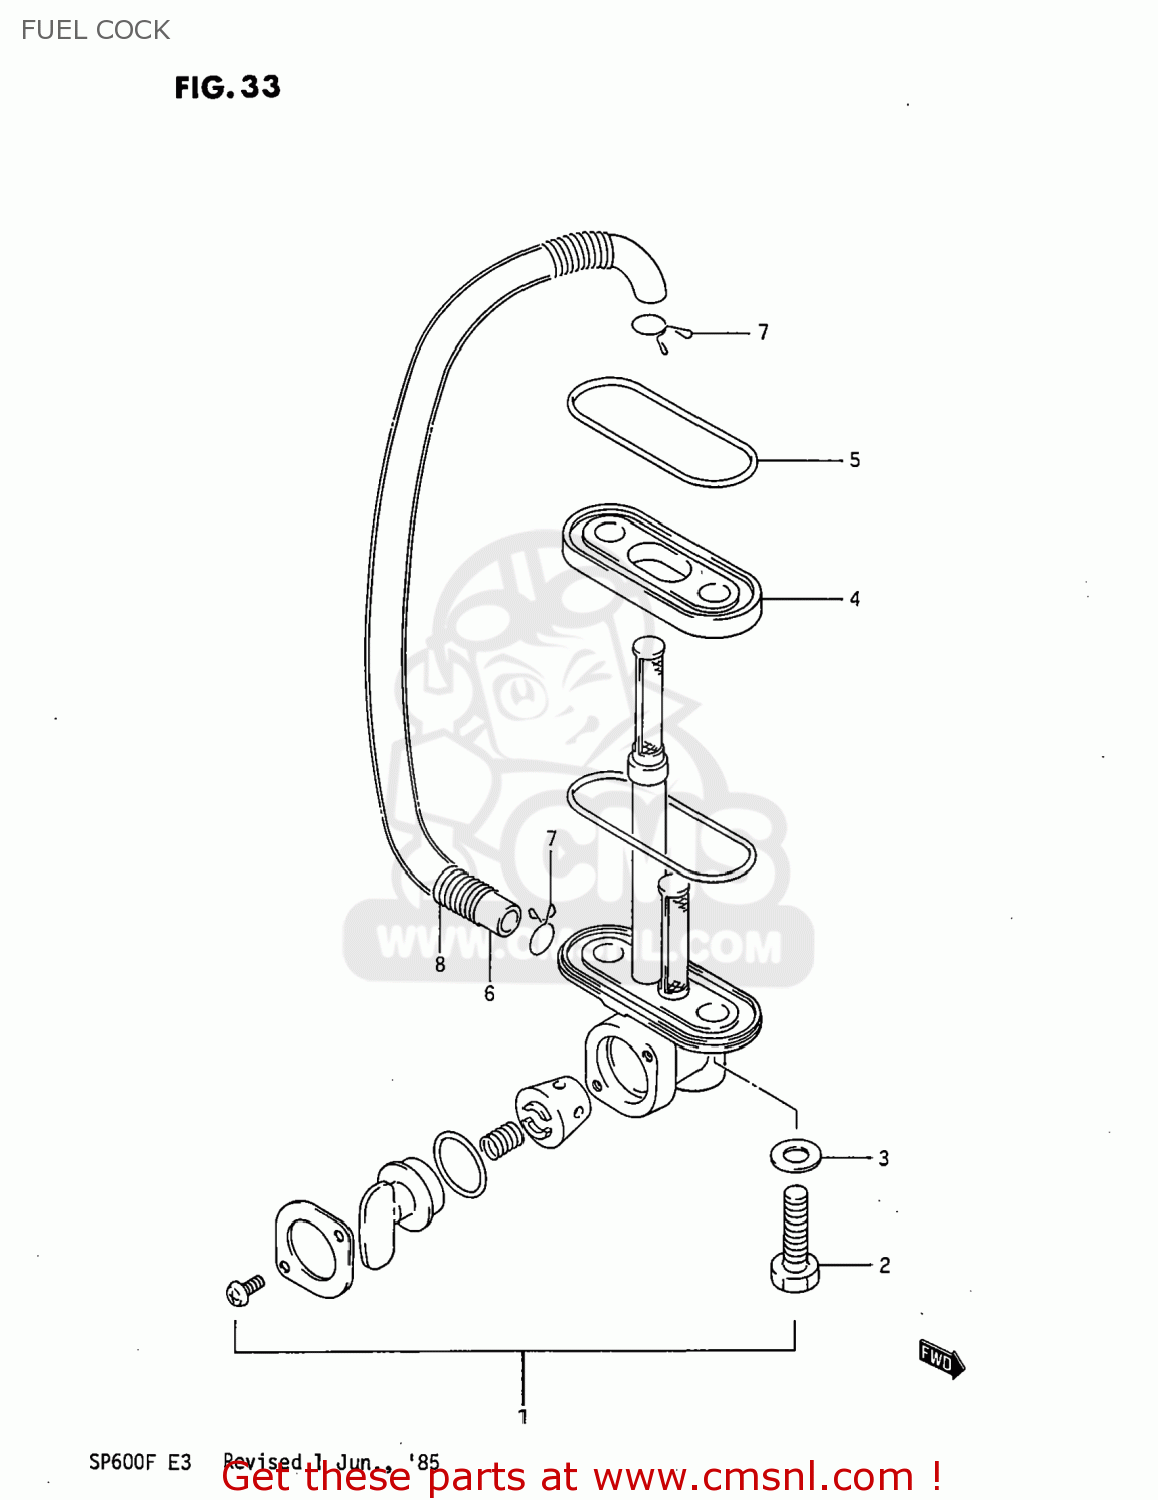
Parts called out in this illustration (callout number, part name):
1	COCK ASSEMBLY,FUEL
2	BOLT(6X20)
3	GASKET
4	SPACER,FUEL COCK
5	GASKET,FUEL COCK (NAS)
6	HOSE
7	CLIP
8	SPRING
